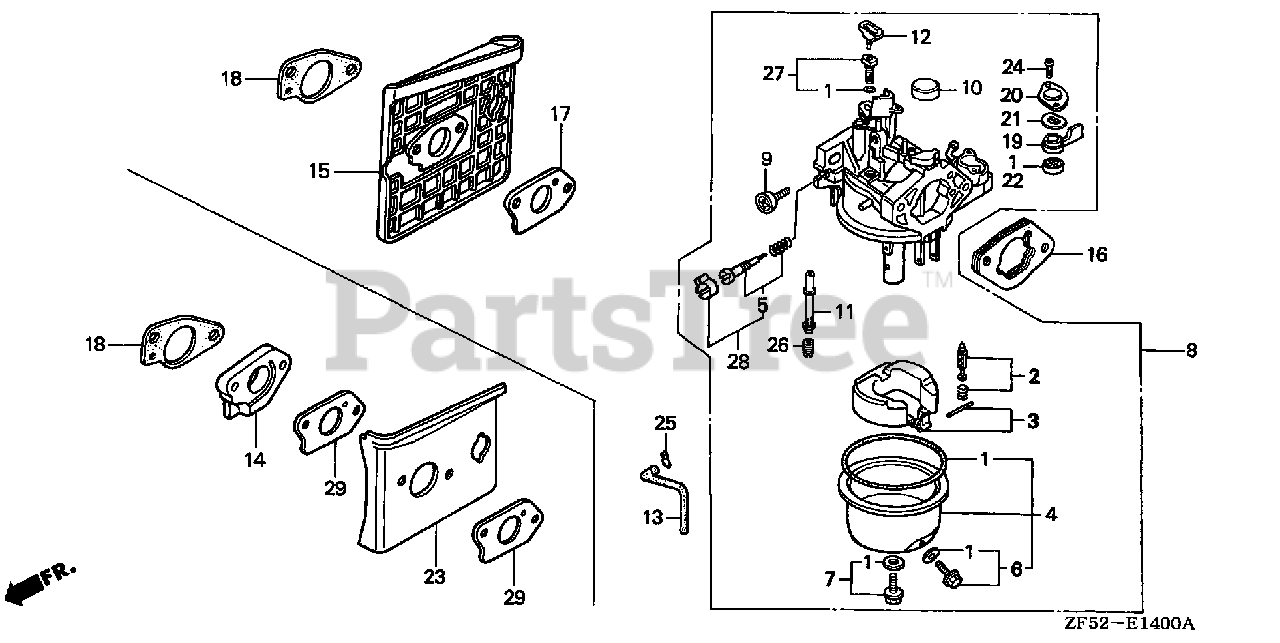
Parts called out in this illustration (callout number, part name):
1	GASKET SET (EXC. 16173-001-004) (EXCEPT 16173-001-004)
2	VALVE SET, FLOAT
4	CHAMBER SET, FLOAT
6	SCREW SET, DRAIN
7	SCREW SET
8	CARBURETOR ASSY. (BE86F B)
9	SCREW, THROTTLE STOP
10	CAP, CHOKE DUST
11	NOZZLE, MAIN
12	COLLAR, SETTING
13	TUBE, AIR VENT (75MM)
15	INSULATOR, CARBURETOR
16	SPACER, CARBURETOR
17	GASKET, CARBURETOR
18	GASKET, INSULATOR
19	LEVER, PETCOCK
20	PLATE, LEVER SETTING
21	SPRING, PETCOCK LEVER
22	GASKET, PETCOCK
24	SCREW, PAN (3X6)
25	CLIP, TUBE (B8)
26	JET, MAIN (#88)
26	JET, MAIN (#90)
26	JET, MAIN (#92)
27	JET SET, PILOT (#40)
28	SCREW SET, PILOT (CARBURETOR NO.)
